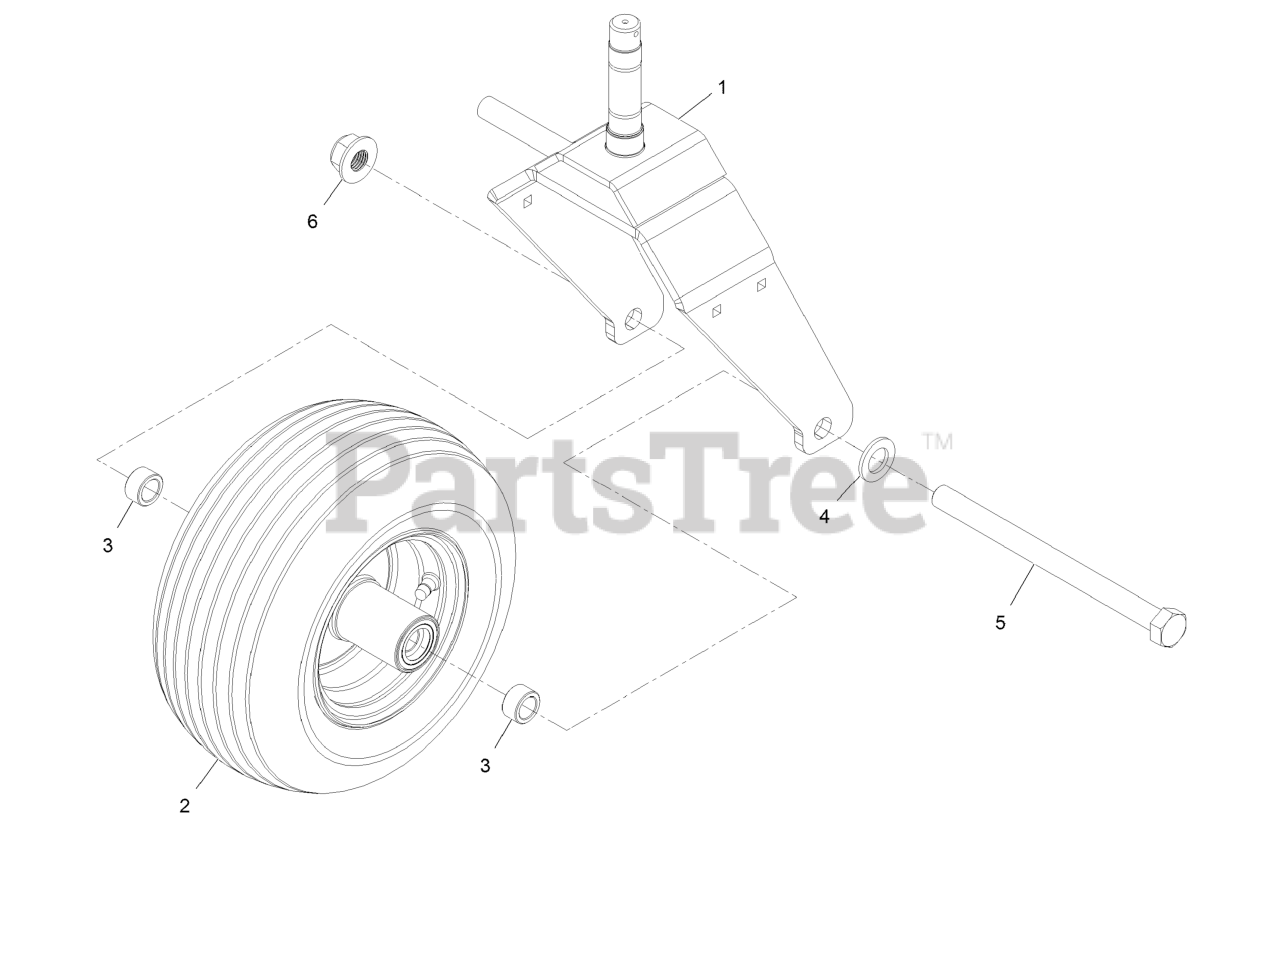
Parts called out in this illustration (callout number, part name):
1	Fork-Caster, LH [red]
2	TIRE, FRONT, ZPLUG,J36,36
3	SPACER-AXLE
5	SCREW-HH
